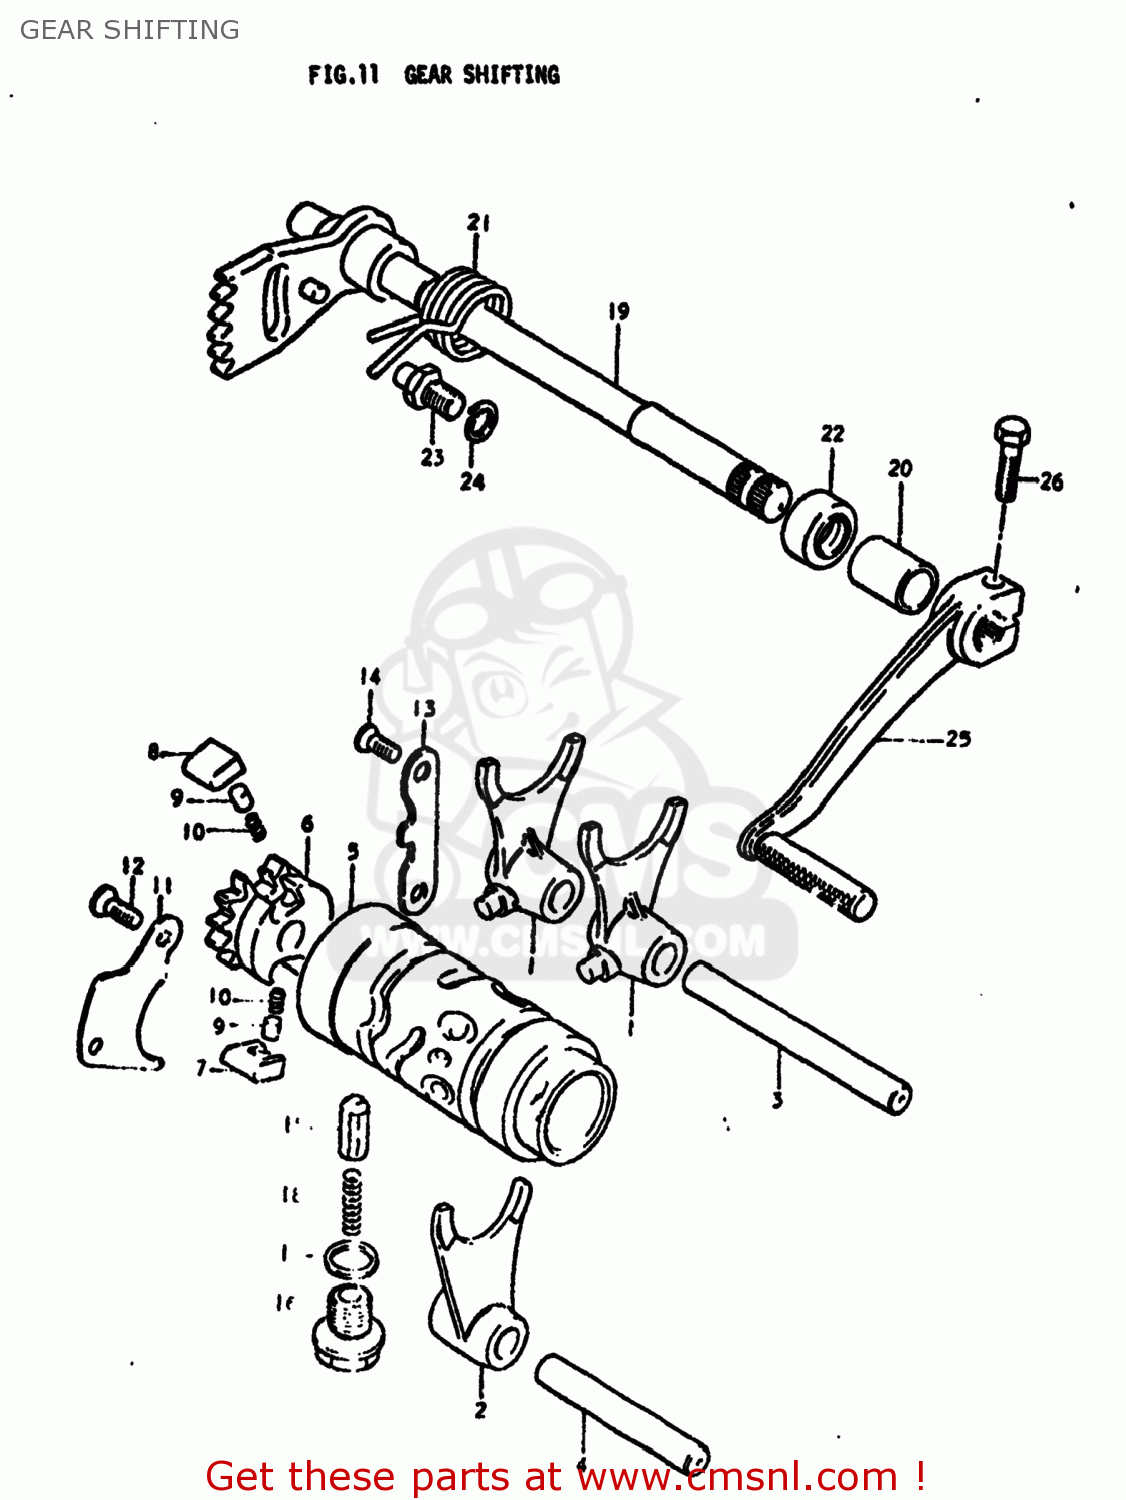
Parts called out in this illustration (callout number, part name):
1	FORK,GEAR SHIFT NO.1
2	FORK,GEAR SHIFT NO.2
3	SHAFT,GEAR SHIFT FORK
4	SHAFT,GEAR SHIFT FORK
5	CAM,GEAR SHIFT
6	RETAINER,GEAR SHIFT CAM
7	PAWL,GEAR SHIFT NO.1
8	PAWL,GEAR SHIFT NO.2
9	PIN(5X8)
10	SPRING
11	LIFTER,GEAR SHIFT PAWL
12	SCREW
13	STOPPER,GEAR SHIFT POLE
14	SCREW
15	STOPPER,GEAR SHIFTING
16	BOLT,GEAR SHAFT CAM STOPPER
17	GASKET(14X19.2X2) (NAS)
18	SPRING
19	SHAFT,GEAR SHIFT
20	CUSHION
21	SPRING
22	OIL SEAL
23	STOPPER,GEAR SHIFT CAM
24	WASHER
25	LEVER ASSEMBLY,GEAR SHIFTING
26	BOLT
